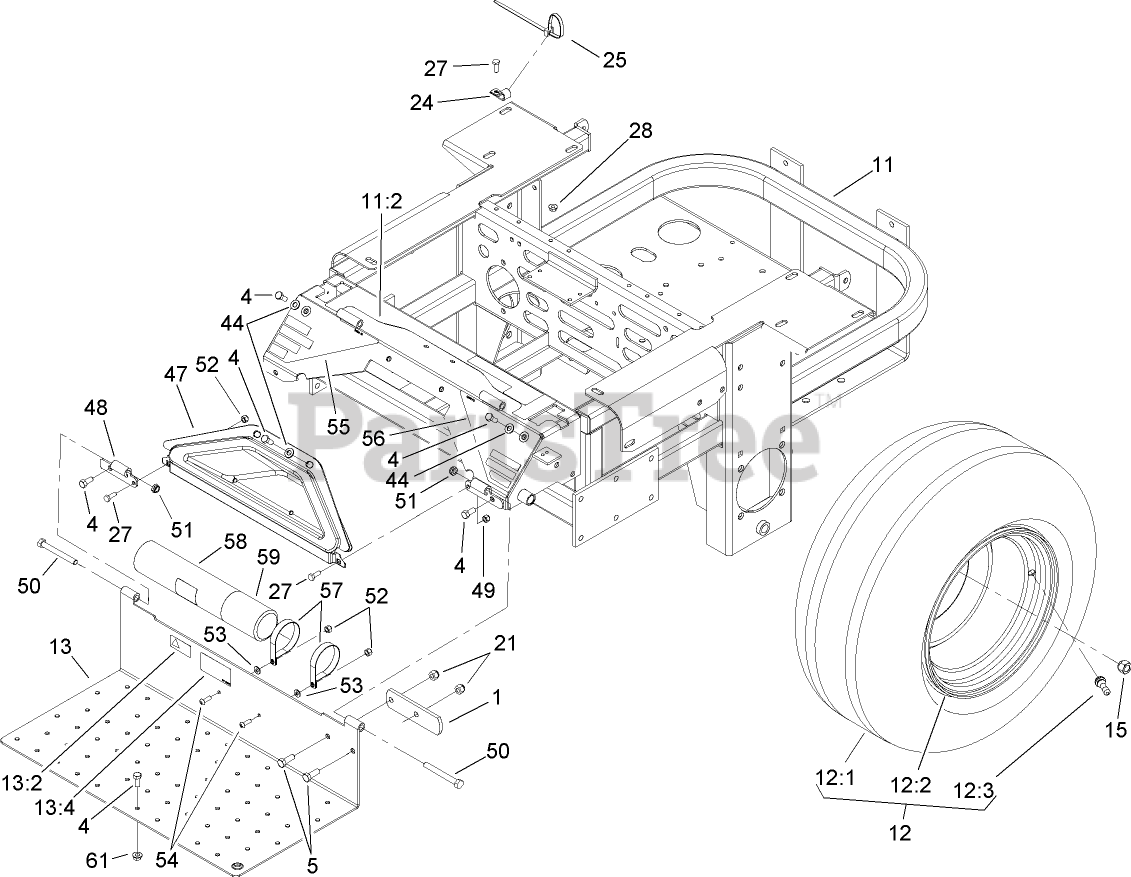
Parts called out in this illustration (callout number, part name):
1	STOP-BRAKE, PARK
4	SCREW-HH
5	SCREW-HH
11	MAIN FRAME ASM
11:2	DECAL-CONSOLE, TOP
12	WHEEL AND TIRE ASM
12:2	WHEEL RIM
12:3	STEM-VALVE
13	FLOORPAN
13:2	DECAL-PROTECTION, EAR
13:4	DECAL-LOCATION, MANUAL
15	NUT-LUG
21	NUT-LOCK, NI
24	CLIP-LOOM
25	TIE-PLASTIC
27	SCREW-HH
28	NUT-HF
44	WASHER-FLAT
47	Pocket
48	Hinge-Floorpan, LH
49	Hinge-Floorpan, RH
50	SCREW-HH
51	NUT-LOCK, NI
52	NUT-LOCK, NI
53	WASHER-FLAT
54	SCREW-PRH
55	DECAL-WARNING, RIGHT
56	DECAL-DANGER, LEFT
57	R-Clamp
58	TUBE-MANUAL
59	CAP-HOUSING
61	NUT-HF
